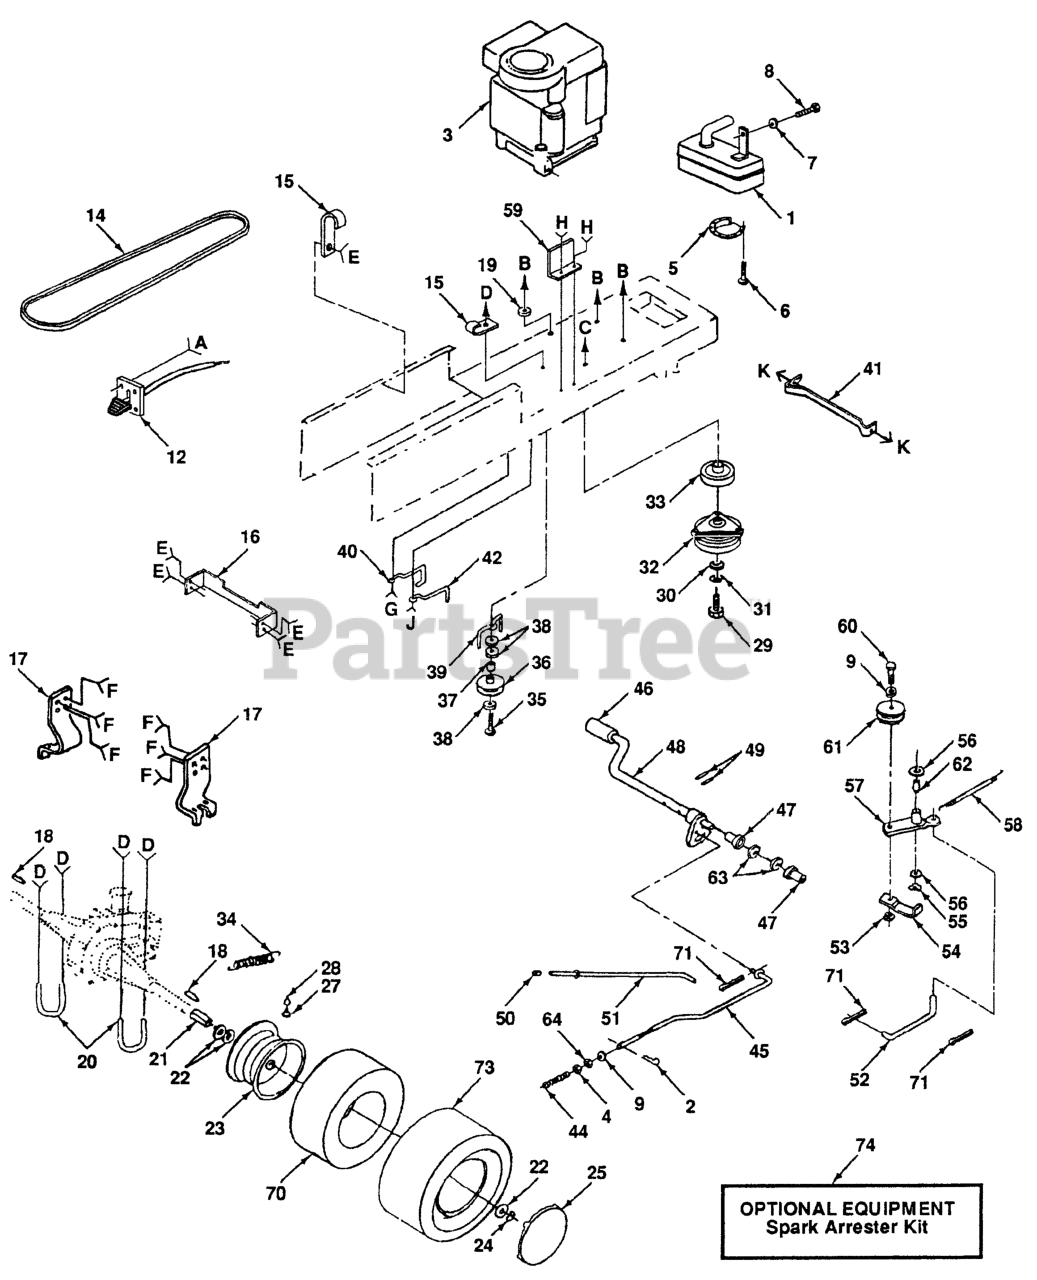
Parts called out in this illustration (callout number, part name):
1	MUFFLER
2	RETAINER M
3	Engine, 14 H.P. Kawasaki
4	NUT
5	DEFL MUFFLER LTV
6	SCREW
7	REPL BY 734 11 53-01
9	WASHER
12	CONT THROT CHOKE
15	CLIP T
16	BRKT,MTG NLA
17	BRKT TRANSAXLE
18	SQUARE KEY
19	WASHER.LOCK.HVY.HLCL.SPR.5/16
21	SPACER SPLIT
23	RIM**
25	CAP,HUB REAR
27	VALVE STEM LT
29	SCREW
31	LOCKWASHER
32	CLUTCH ELEC HYT
33	ENGINE PULLEY YT
34	SPRING T
36	FLAT IDLER PULLEY
37	SPACER T
38	WASHER
39	BELT KEEPER LT NLA
40	KEEPER BELT ENGLH
41	KIT RETAINER YTH
42	KEEPER,BLT ENG LT
44	SPRING ROD LT
45	ROD BRAKE
46	COVER, PEDAL (1 2)
47	BEARING.NYLON
48	SHAFT FOOT PEDAL
49	PIN.ROLL.3/16 X 1"
50	CAP
51	ROD BRAKE PARK
52	LINK, CLUTCH LT
53	LOCKNUT
54	RETAIN BELT
58	SPRING, RETURN LT
59	BRACKET LT
60	BOLT
61	IDLER PULLEY
62	BEARING LT (2 2)
63	WASHER LT
64	NUT
70	TUBE
71	COTTER PIN
73	TIRE HEAVY DUTY
74	SPARK ARREST
